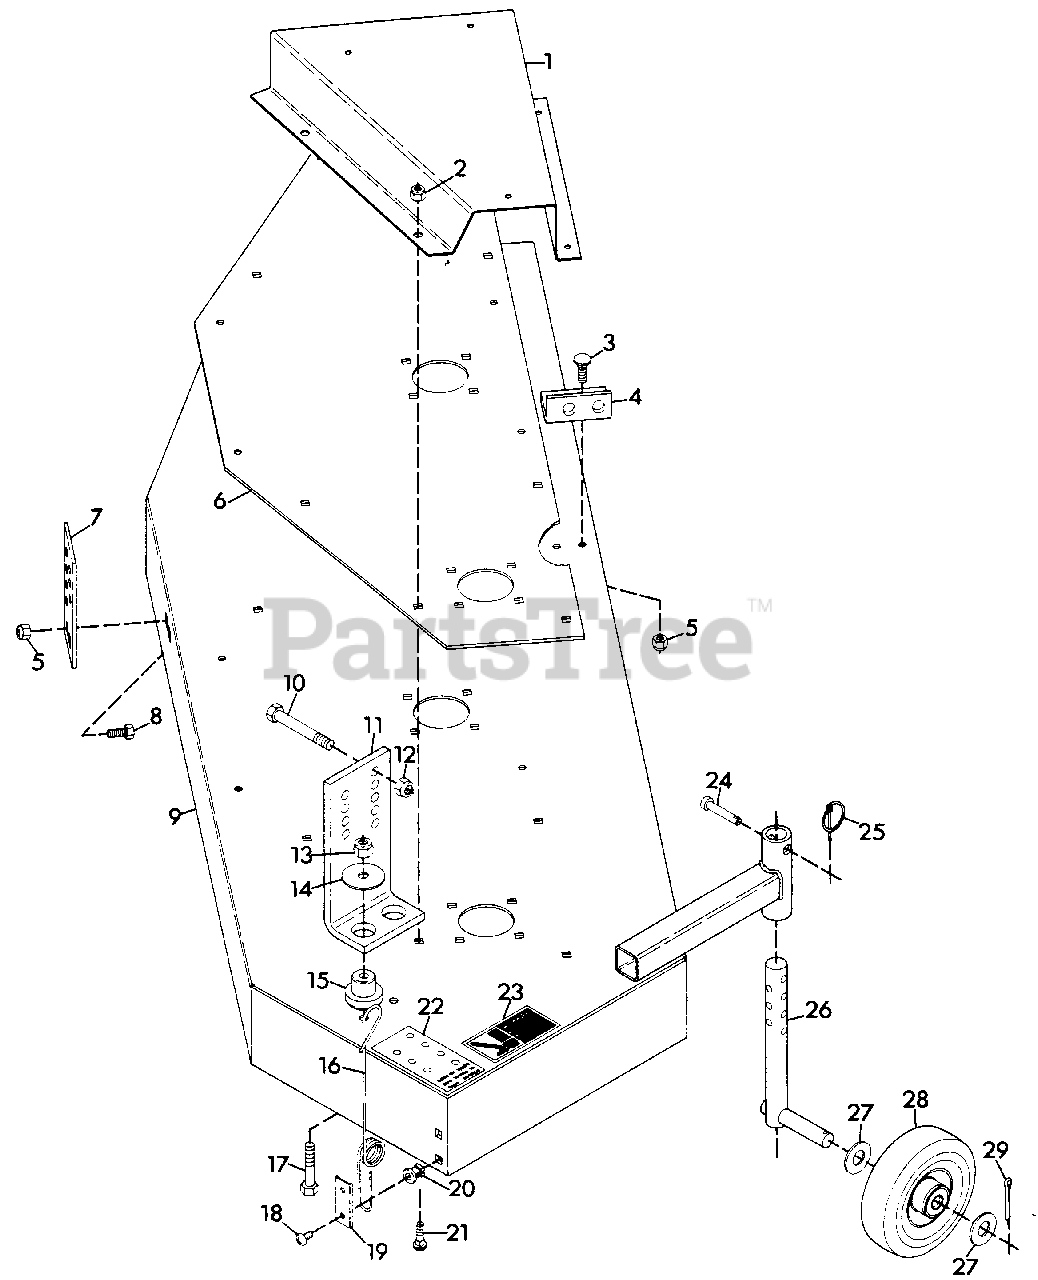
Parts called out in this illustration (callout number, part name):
1	COVER, L.H. BELT
1	COVER, R.H. BELT
2	NUT, LOCK 5/16-18
3	BOLT, 3/8-16X1 RD HD SQ NK
4	BRACKET, IDLER ROD
5	NUT, LOCK 3/8-16
6	PLATE, DECK SUPPORT
7	BRACKET, ADJUSTMENT
8	BOLT, HEX 3/8-16X1.00
9	WELDMENT, DECK
10	BOLT, HEX 1/2-13X3.25
11	BRACKET, HEIGHT ADJUSTMENT
12	NUT, LOCK 1/2-13
13	NUT, LOCK 7/16-14
14	WASHER, FLAT .45X2.00X.080
15	MOUNT, FRONT MOTOR
16	SPRING, TORSION
17	BOLT, HEX 7/16-14X2.25
18	SCREW, TAPPING 1/4-20X.625 P/HD
19	CLAMP
20	GROMMET, PLASTIC
21	BOLT, 5/16-18X.875 RD HD SQ NK
22	DECAL, BELT DIAGRAM
23	DECAL, DANGER FOOT
24	PIN, CLEVIS 3/8X2.62
25	KLIK PIN
26	WELDMENT, CASTER WHEEL AXLE
27	WASHER, FLAT .813X1.37X.100
28	WHEEL, CASTER
29	PIN, COTTER 1/8X1.25
NS	DECAL, DANGER HAND
NS	DECAL, WARNING EYE
